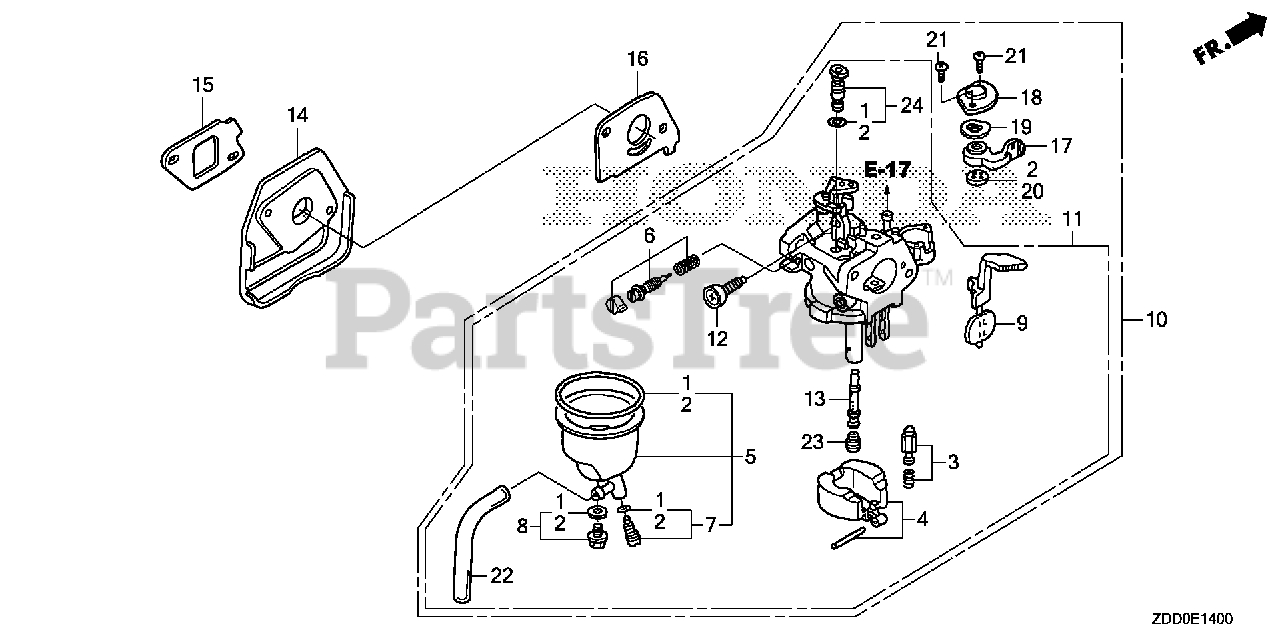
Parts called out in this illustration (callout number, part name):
2	GASKET SET
3	VALVE SET, FLOAT (CARBURETOR NO.) (SEAT NOT INCLUDED)
5	CHAMBER SET, FLOAT (CARBURETOR NO.)
6	SCREW SET (Honda Code 4219879). (CARBURETOR NO.)
7	SCREW SET, DRAIN (CARBURETOR NO.)
8	SCREW SET (CARBURETOR NO.)
9	CHOKE SET (CARBURETOR NO.)
9	CHOKE SET
10	CARBURETOR ASSY. (BF32H B)
10	CARBURETOR ASSY. (BF32Q A)
12	SCREW, THROTTLE STOP
13	NOZZLE, MAIN
14	INSULATOR, CARBURETOR
15	GASKET, INSULATOR
16	GASKET, CARBURETOR
17	LEVER, PETCOCK
18	PLATE, LEVER SETTING (CARBURETOR NO.)
19	SPRING, PETCOCK LEVER (CARBURETOR NO.)
20	GASKET, VALVE
21	SCREW, PAN (3X6)
22	BULK HOSE, VINYL (3.5X6.5X8000) (9500(95003-05001-60M) (CARBURETOR NO.)
23	JET, MAIN (#55) Use from Engine SN BF22B D.
23	JET, MAIN (#58) Use from Engine SN BF22B D.
23	JET, MAIN (#60)
23	JET, MAIN (#62) (CARBURETOR NO.)
24	JET SET, PILOT (#35)
24	JET SET, PILOT (#40) (ADVENTURE GREEN) (CARBURETOR NO.)
